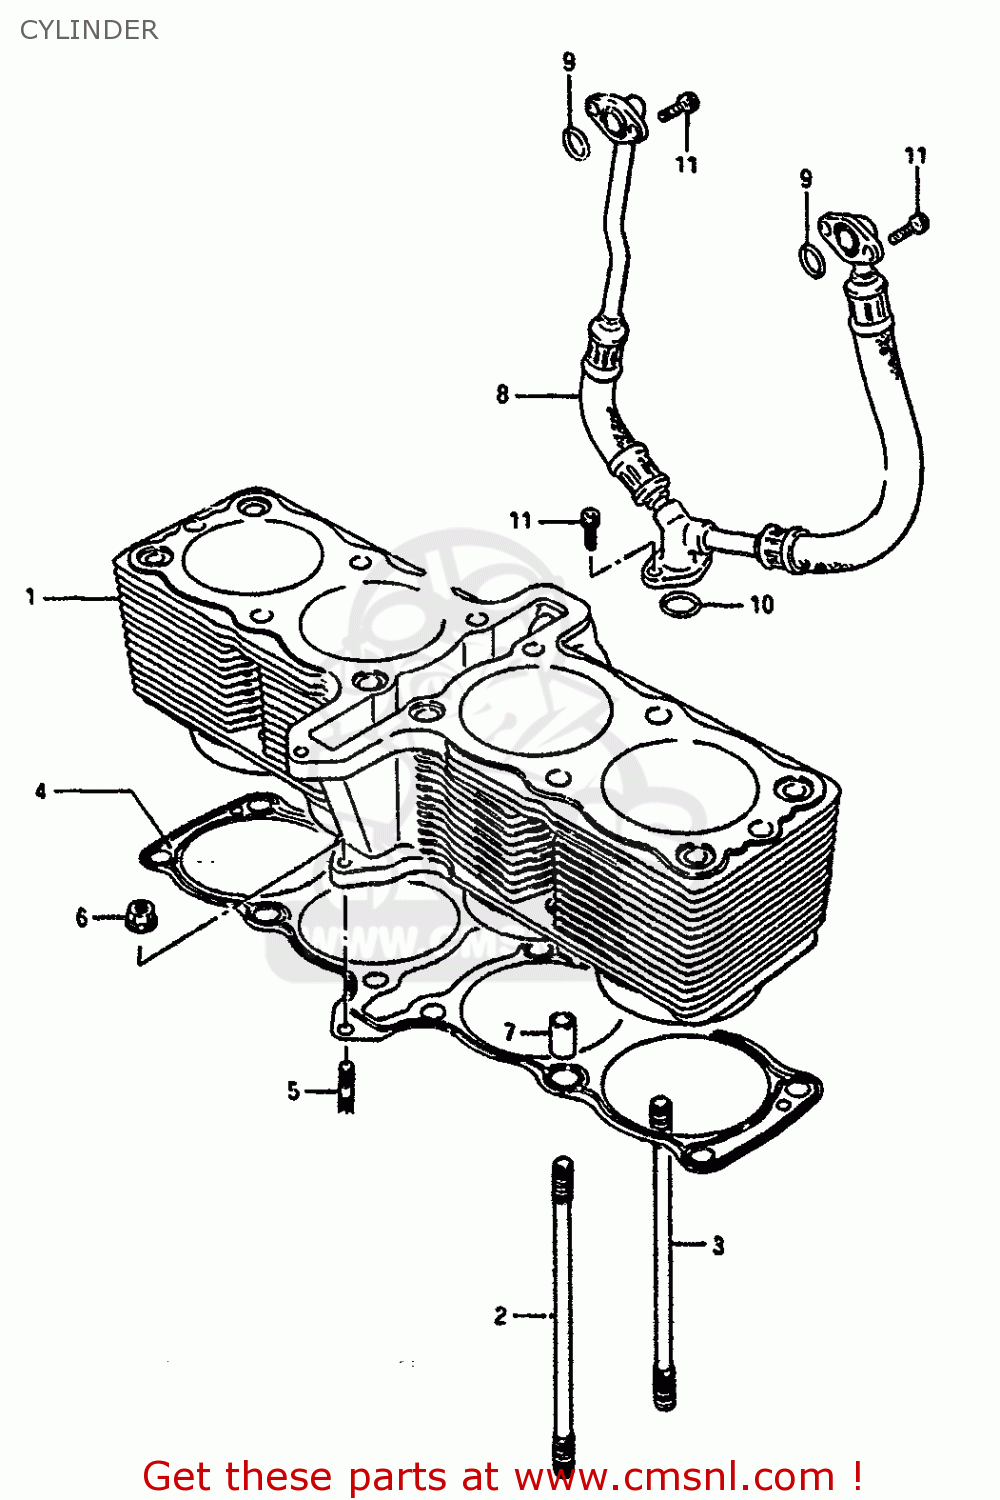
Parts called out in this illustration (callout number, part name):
1	CYLINDER
2	BOLT,STUD
3	STUD
4	GASKET,CYLINDER (NAS)
5	STUD BOLT L:20
6	NUT 6MM
7	PIN
8	HOSE
9	O RING(D:2.5,ID:13.8)
10	O RING(D:2.4,ID:15.8)
11	BOLT
